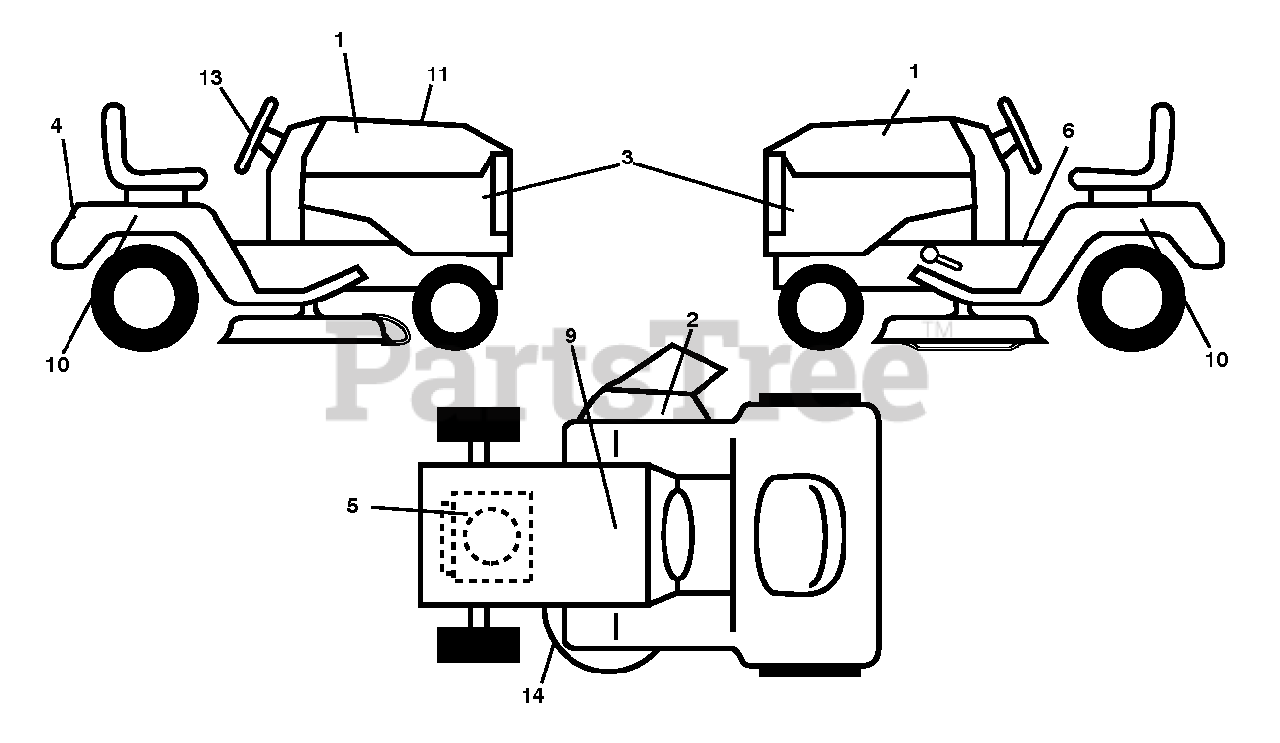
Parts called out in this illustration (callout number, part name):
2	DECAL.WARN.KEEP.HAND.AWAY
5	DECAL.ENG.BS.22.XRD.TWN.278445
6	Fender Warning Decal, English
9	DECAL BTRY SYMBOLS
13	DECAL.STEER.WHEEL.POULAN.PRO
14	DECAL V BELT SCHEMATIC
